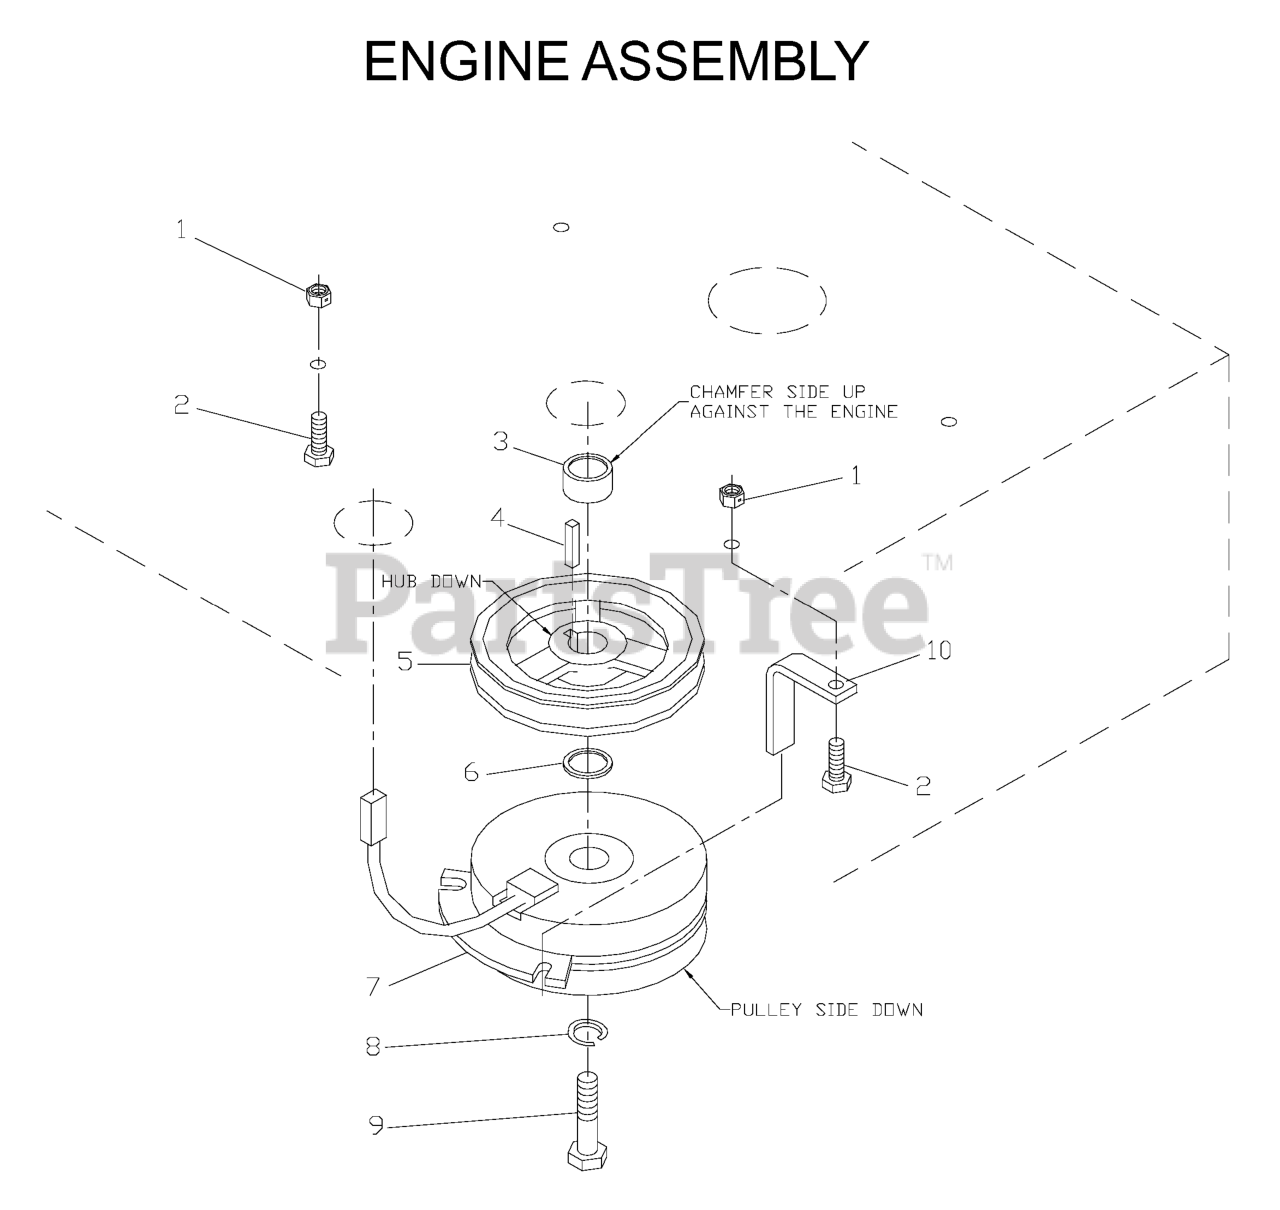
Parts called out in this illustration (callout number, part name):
1	NUT 5/16C CENTERLOCK
2	HCS 5/16C X 1 1/4
4	KEY 1/4 SQ X 1 1/8
6	BUSHING, 10GA MACHINERY
7	CLUTCH, ELECTRIC
8	WASHER 7/16 LOCK
9	BOLT 7/16F X 2 1/2
10	HCS 5/16C X 1 3/4
11	CLUTCH TIE DOWN
